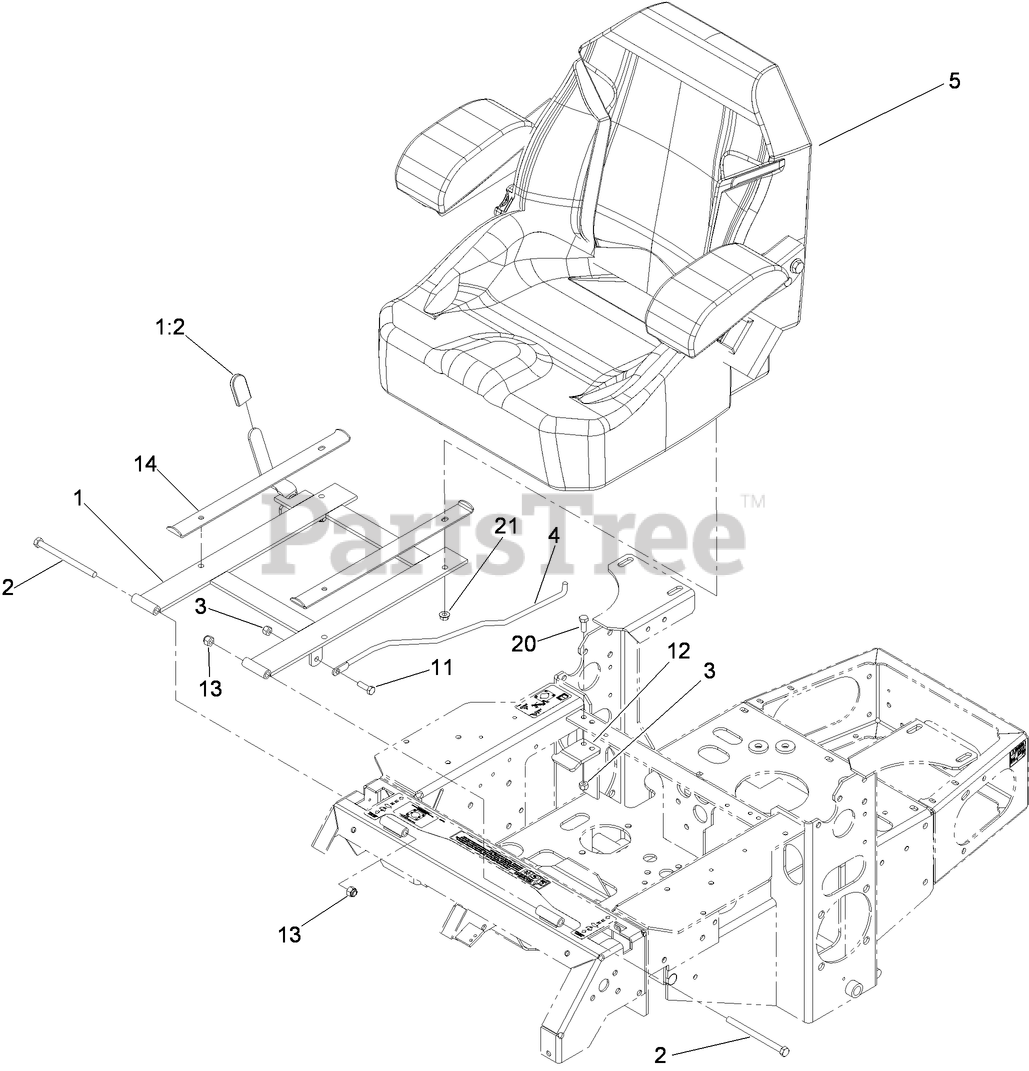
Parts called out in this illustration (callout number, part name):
1	SEAT FRAME AND LATCH ASM
1:2	GRIP-LEVER
2	SCREW-HH
3	NUT-LOCK, NI
4	ROD-RETAINER, SEAT
5	SEAT-STANDARD
11	SCREW-HH
12	CATCH-LATCH, SEAT
13	NUT-LOCK, NI
14	STOP-SEAT
20	SCREW-HH
21	NUT-HF
